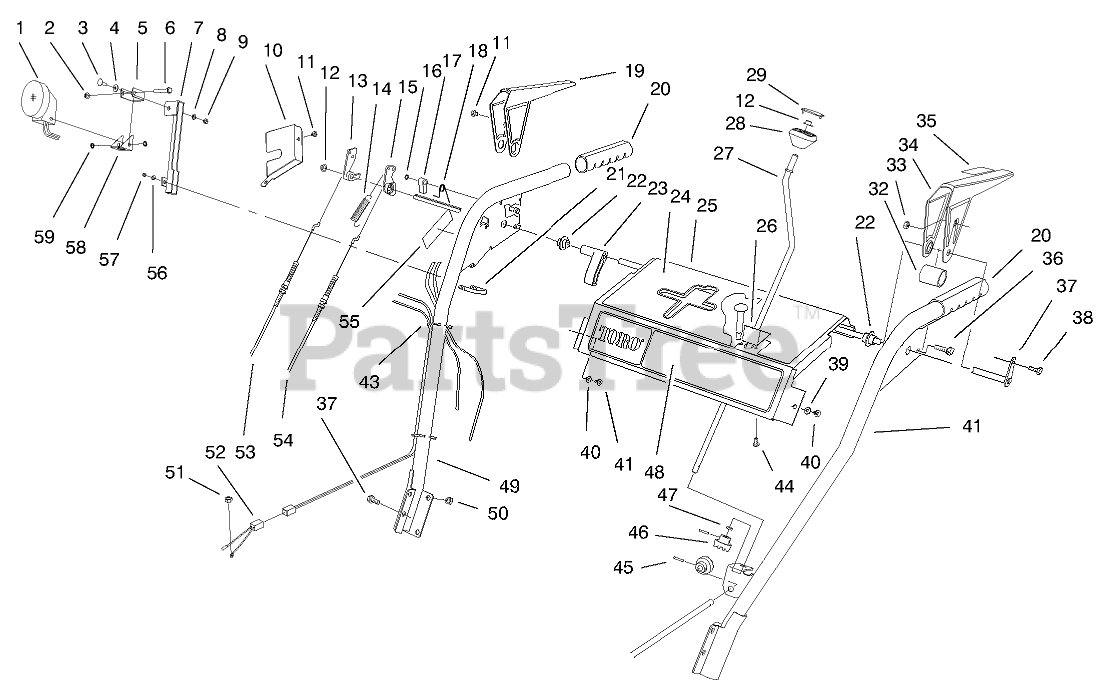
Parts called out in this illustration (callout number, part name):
1	HEADLAMP ASM
2	NUT-HF
3	BOLT-CARR
4	WASHER-FLAT
5	BRACKET
6	SCREW-HH
7	LIGHT MOUNT ASM
8	WASHER-LOCK
9	NUT-HEX
10	COVER-LOCK, LEVER
11	SCREW-HH
12	RETAINER-PUSH ON
13	TANG-LOCKING
14	SPRING-EXTENSION
15	CAM-RELEASE
16	E-RING-RETAINER
17	LATCH-LOCKING
18	SPRING-TORSION
19	LEVER-TRACTION, RH
20	GRIP-HANDLE
21	U-BOLT
22	BUSHING-LEVER
23	LEVER-TRIP
24	DECAL-PANEL, TOP
24	DECAL-CONTROL
25	CONTROL PANEL/DECAL ASM (38558)
25	CONTROL PANEL/DECAL ASM (38559)
26	PLATE-GUIDE
27	CRANK-ROD, CHUTE
28	KNOB-CONTROL, CHUTE
29	COVER-KNOB
32	SPACER-LEVER, TRACTION
33	NUT-LOCK, NI
34	LEVER-TRACTION, LH
35	DECAL-LEVER
36	SCREW-HWHTF
37	CROSS ROD ASM
38	SCREW-HWH
39	WASHER-FLAT
40	SCREW-HWHTF
41	LH HANDLE ASM
43	TIE-CABLE
44	SCREW
45	PIN-SPRING
46	GEAR-UNIVERSAL
47	WASHER-RUBBER
48	DECAL - FRONT PANEL
49	RH Handle ASM, 24"-32"
50	NUT-LOCK, NI
51	NUT-HEX
52	WIRE ASM
53	CABLE-IMPELLER
54	CABLE-TRACTION
55	DECAL-WARNING
55	DECAL-ADJUSTMENT
56	WASHER-PLAIN
57	NUT-LOCK, NI
58	TO BE DISCONTINED-NOT NEEDED ON PRODUCT
59	WASHER-LOCK
